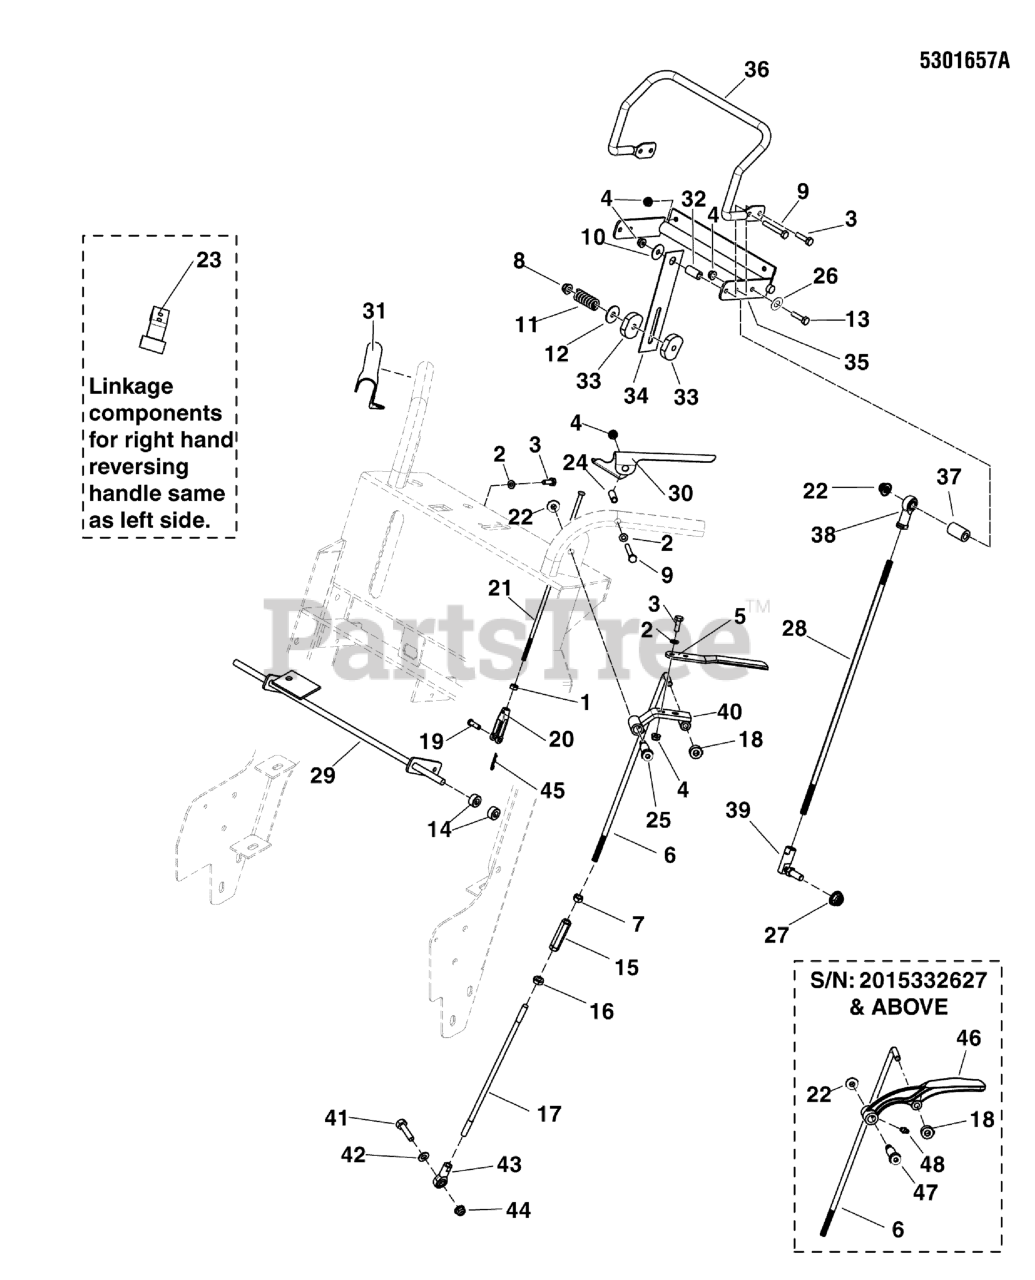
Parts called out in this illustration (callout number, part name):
1	HN, 1/4F GR5 YZ
2	WASHER, 1/4 SAE
3	BOLT, 1/4-20 X 3/4 GD5 YZ
4	NUT, 1/4-20 HEX NYLOCK FLANGE
6	ROD, REVERSING, HD1648
7	NUT, 5/16-24 HEX, LH
8	NUT, 5/16-18 HEX NYLOCK FLANGE
9	BOLT, 1/4-20 X 1-3/4" GD5 YZ
10	WASHER, 1/4" FENDER
11	SPRING-COMP, .428IDX2.50LGX.154WR, BZ
12	WASHER, 5/16" FENDER
13	BOLT, 3/8-16 X 2-1/2" GD5 CZ
14	COLLAR, 3/8" SET
15	ADJUSTER, ROD LINKAGE 5/16-24
16	NUT, 5/16-24 HEX
17	ROD, 5/16 X 13.75 TBE
18	COLLAR, 5/16" SET
19	PIN, CLEVIS, 1/4 X 7/8, PLATED
21	ROD, OPC LINK, HD1648
22	NUT, 3/8-16 HEX NYLOCK FLANGE
23	WELD, REVERSE HANDLE - RH
24	SPACER, .26 X .38 X 1.250, YZ
25	BOLT, 3/8-16 x 1-1/2", 1/2" SHOULDER
26	WASHER, 3/8 SAE
27	NUT, 3/8-24 HEX NYLON LOCK
28	ROD, CRUISE CONTROL, HD1648
29	WELD, OPC SHAFT- RED
32	SPACER, .26 X .50 X 1.00 YZ
33	SPACER, .34 X 1.54 X .25 UHMW
34	PLATE, FRICTION CONTROL
35	WELD, SPEED CONTROL,HD1648 - RED
36	BAR, SPEED CONTROL, DIPPED
37	SPACER, .38 X .75 X 1.25, YZ
38	ROD END, 3/8-24 LH FEMALE
39	BALL JOINT, 3/8-24 FEM, STUD.
40	WELD, REVERSE HANDLE - LH
41	BOLT, 5/16-18 X 1-1/4 GD5 TFL, CZ
42	WASHER, 5/16" SAE
43	BALL JOINT 5/16-24 RH FEMALE BRONZE RACE
44	NUT, 5/16-18 HEX NYLOCK FLANGE
45	PIN, HAIR, .0585 X 1-1/8, 1/4 EYE, YZ
46	HANDLE, REVERSING - BLK
47	BOLT, 3/8-16 X 1, 1/2 SHOULDER
48	GREASE FITTING, 1/4-28 STRAIGHT
